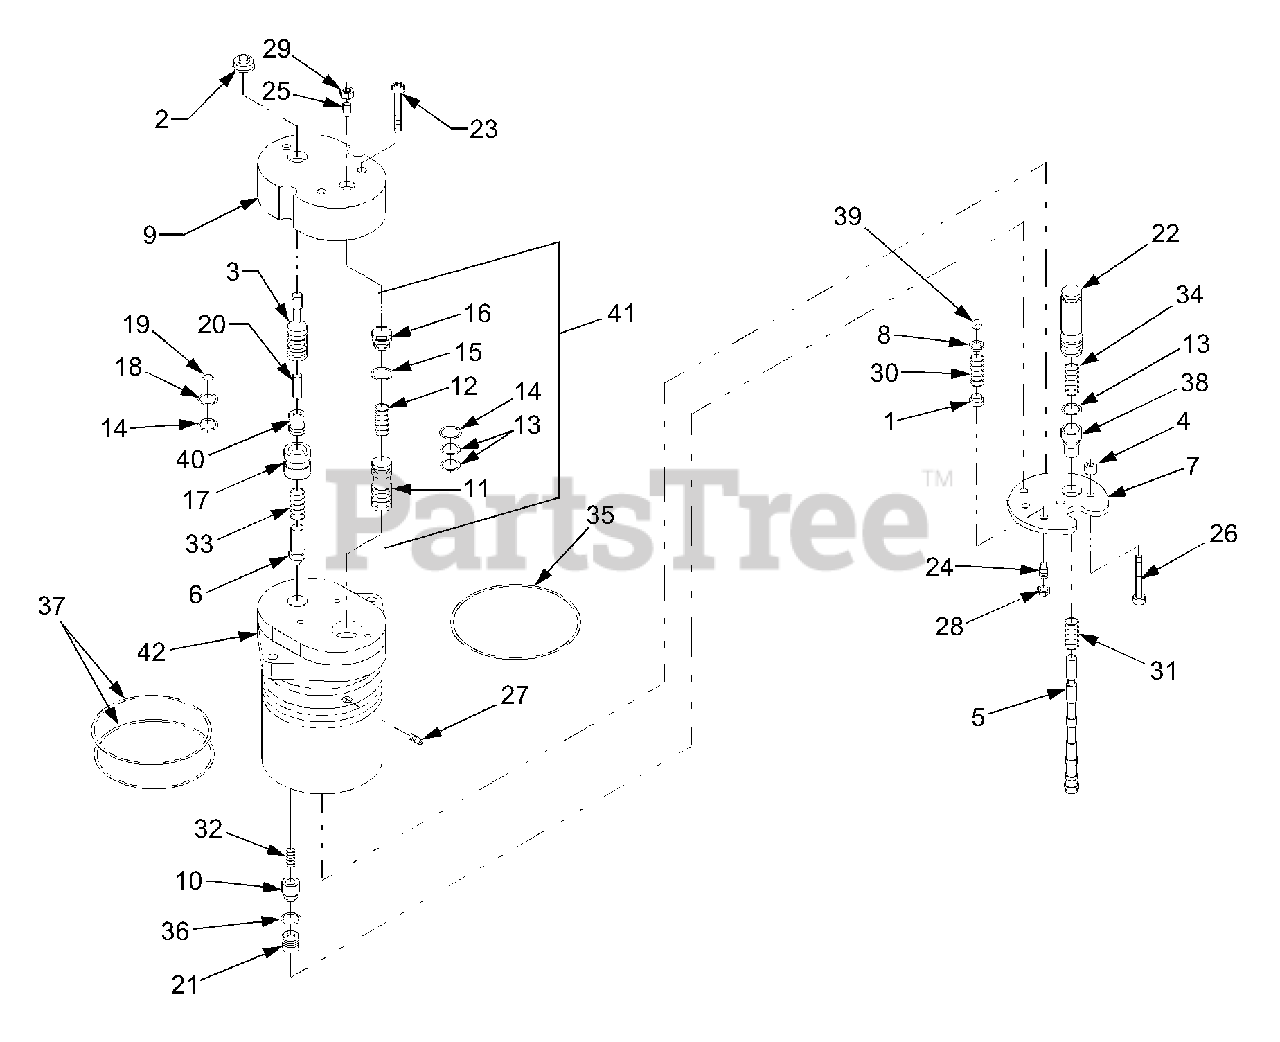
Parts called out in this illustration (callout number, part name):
2	Rubber, Guard
5	Spool
22	Valve
42	Body, Valve
